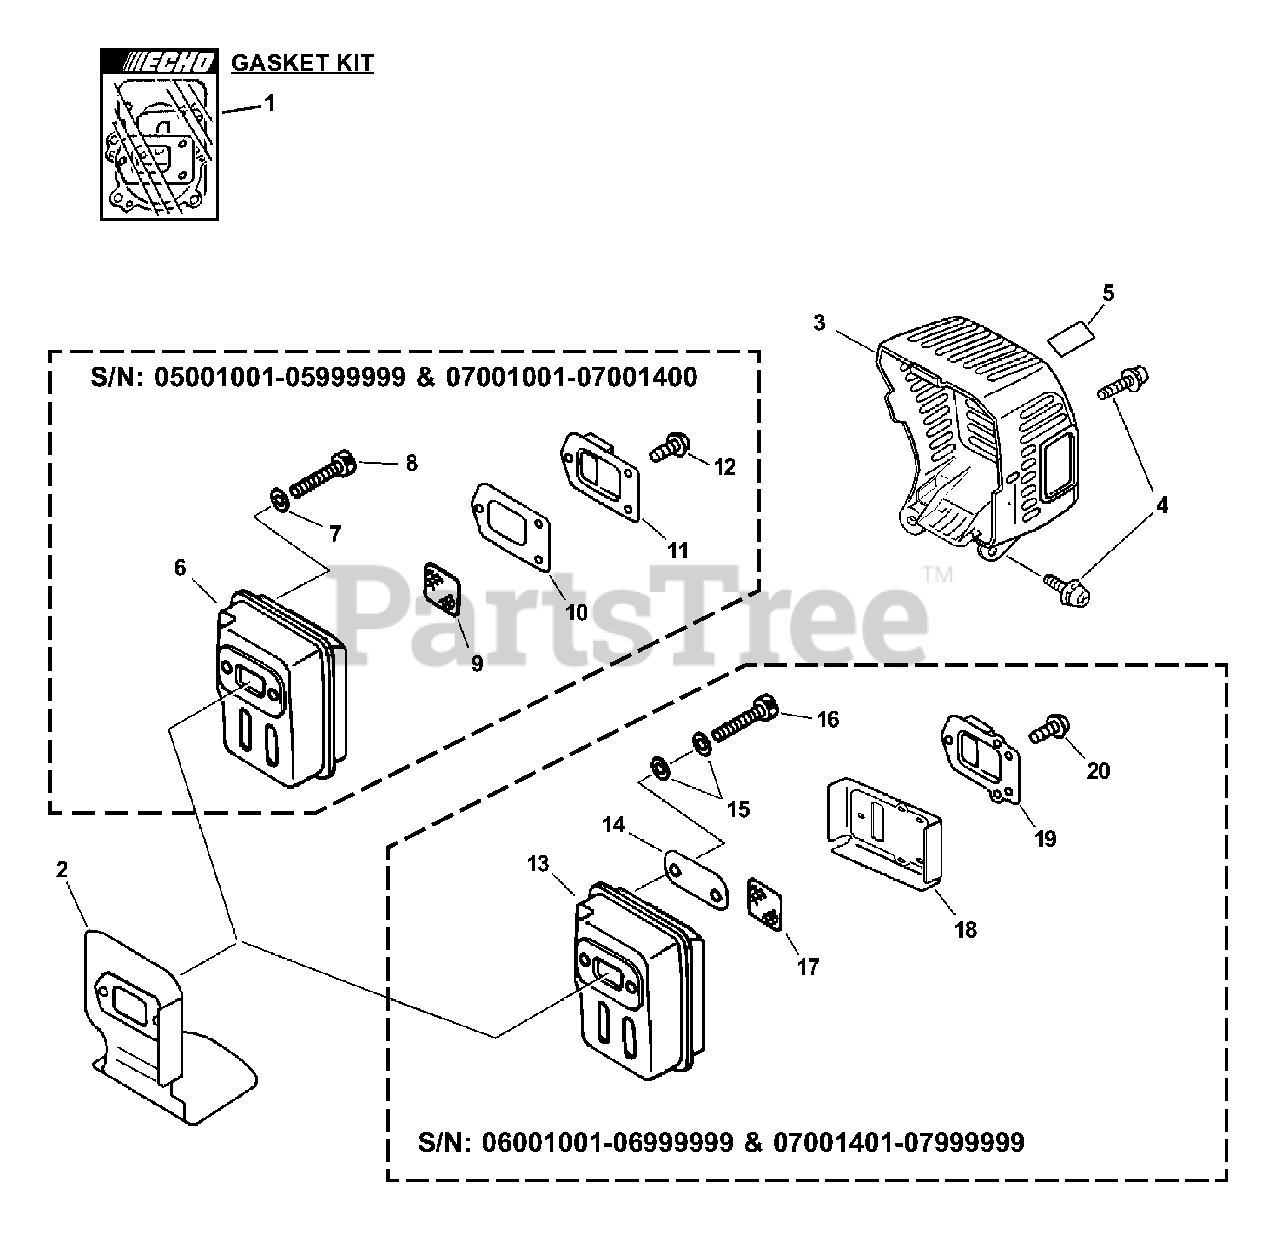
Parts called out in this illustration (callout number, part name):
1	GASKET KIT
2	SHIELD, EXHAUST
3	COVER, EXHAUST
4	SCREW - 5X12
5	LABEL - HOT SURFACE
7	WASHER - 5
8	SCREW - 5X55
9	SCREEN, SPARK ARRESTOR
10	GASKET, EXHAUST
11	GUIDE, EXHAUST
12	SCREW - 4X10
13	MUFFLER
15	WASHER - CONICAL
16	SCREW - 5X55
17	SCREEN, SPARK ARRESTOR
18	GASKET, EXHAUST
19	GUIDE, EXHAUST
20	SCREW - 4X10
